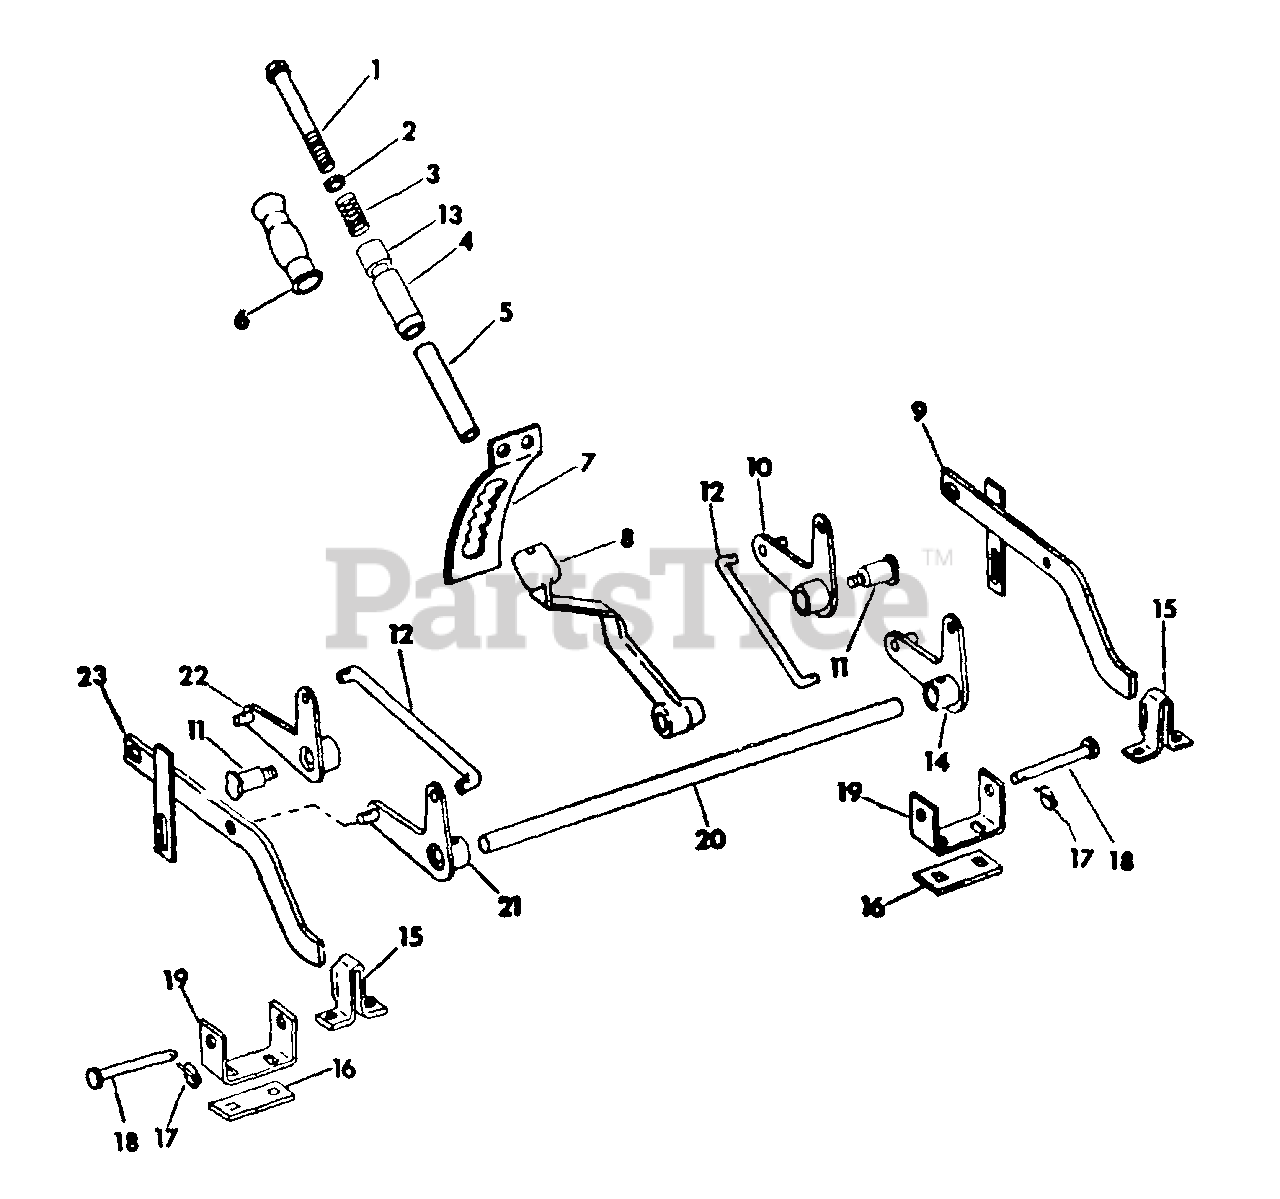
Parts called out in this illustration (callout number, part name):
1	SCREW, 3/8-16 X 6-1/4 ZND HEX-HD CAP
2	WASHER, SPRING RETAINING
3	SPRING, COMPRESSION
4	BUSHING, LIFT
5	BUSHING, LIFT HANDLE
6	GRIP, HANDLE
7	SECTOR, LIFT HANDLE
9	SUPPORT ASSY, RH LIFT BAR
10	ARM ASSY, RH FRONT LIFT
12	ROD, CONNECTING LINK
13	BUSHING, LIFT HANDLE
14	ARM ASSY, RH REAR LIFT
15	CHANNEL, LIFT BAR REAR GUIDE
16	PLATE, STIFFENER
17	PIN, KLIK
19	CLEVIS, LOCK PIN FRT BRACKET
21	ARM ASSY, LH REAR LIFT
22	ARM ASSY, LH FRONT LIFT
23	SUPPORT ASSY, LH LIFT BAR
